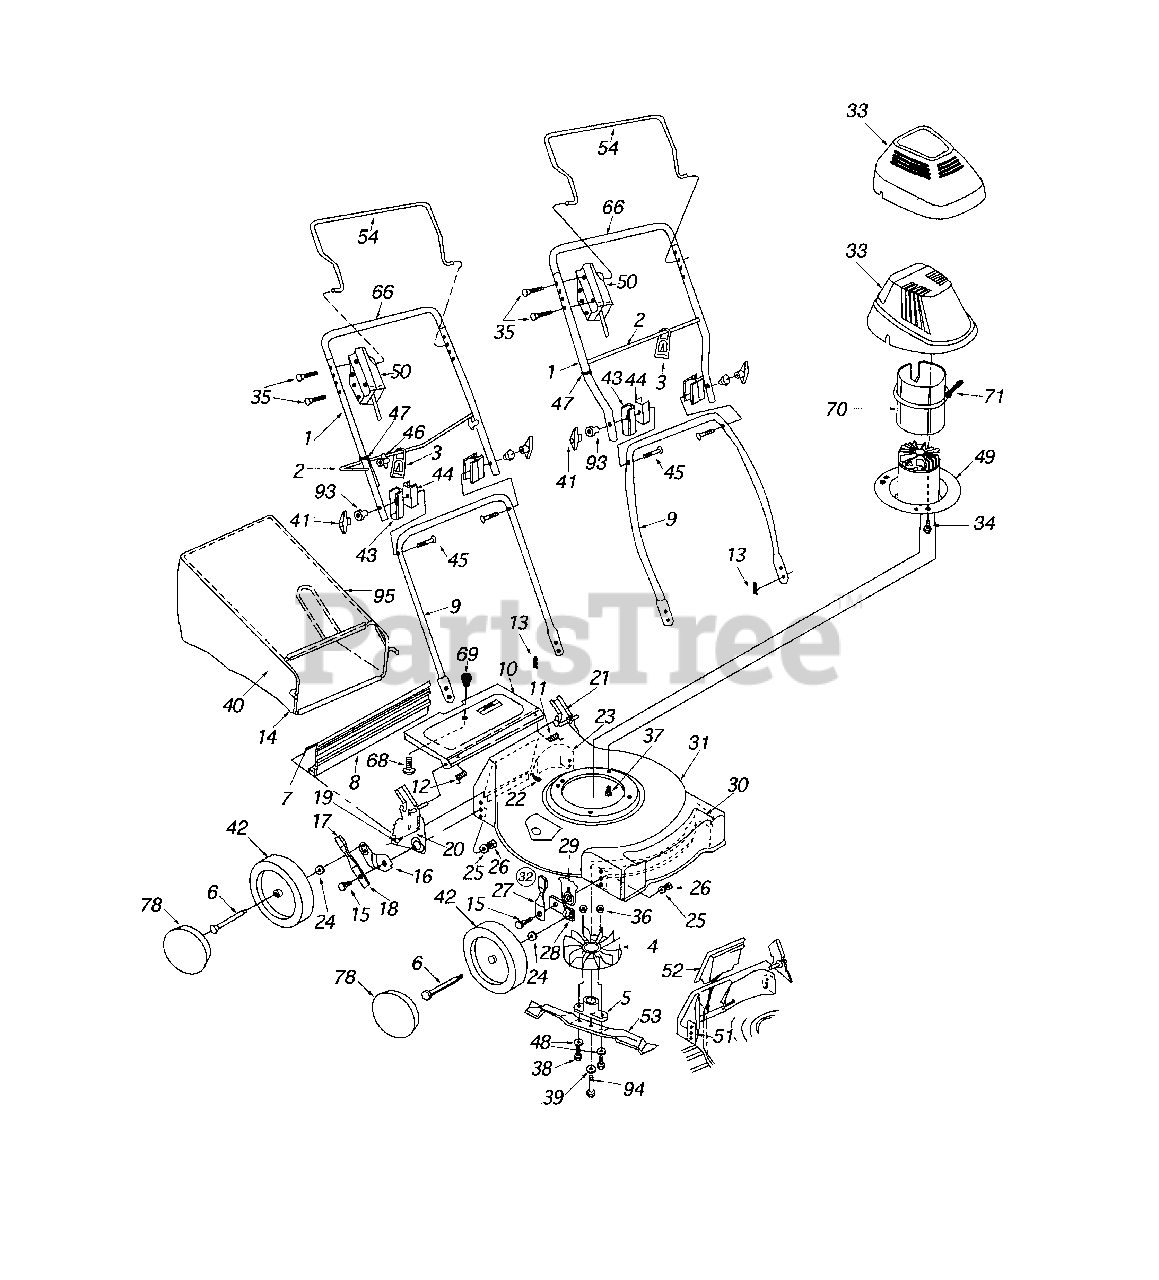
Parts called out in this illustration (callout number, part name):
3	Strain-Relief Cord
4	Armature Fan
5	Blade Adapter
6	Axle Bolt
7	Rear Flap Wire
8	Rear Flap
12	Door Spring (R.H.)
13	Hairpin Clip
16	Pivot Bar: 9 Position (R.H.)
17	Spring Lever Knob
18	Spring Lever
19	Hex AB-Tap Scr.
22	Torx . Mach. AB-Tap Scr.
25	Bell Washer .39" I.D. x 1.38" O.D.
26	Hex Nut 3/8-16 Thd.
27	Spring Lever Ass'y. W/Knob
29	Height Adj. Plate
33	Motor Cover
34	Scr. #10-24 x .75" Lg.
35	C-Sunk Scr. 1/4-20 x 1.8" Lg.
36	Hex Nut 3/8-24 Thd.
37	Hex Tt-Tap Scr. 3/8-16 x 1" Lg.
38	Hex Bolt 3/8-24 x 1.25" Lg.
39	Bell Washer .396" I.D. x 1.14"
40	Grass Bag (Private Label Logo)
41	Grass Bag w/Logo
42	Plastic Knob
43	Wheel Ass'y. Comp.
44	Upper Handle Insulator
45	Lower Handle Insulator
46	Carriage Bolt 5/16-18 x 3" Lg.
47	Cable Tie
48	Bell Washer 3/8" I.D.
49	Motor, Cord & Switch Ass'y.
50	Cord & Switch Ass'y. Comp.
53	19" Mulching Blade
68	Truss Scr. #10-24 x .38" Lg.
70	Insulator Motor Hsg.
71	Cable Tie
78	Hub Cap
93	Insulator Knob
94	Hex Bolt 3/8-24 x 2.5"
